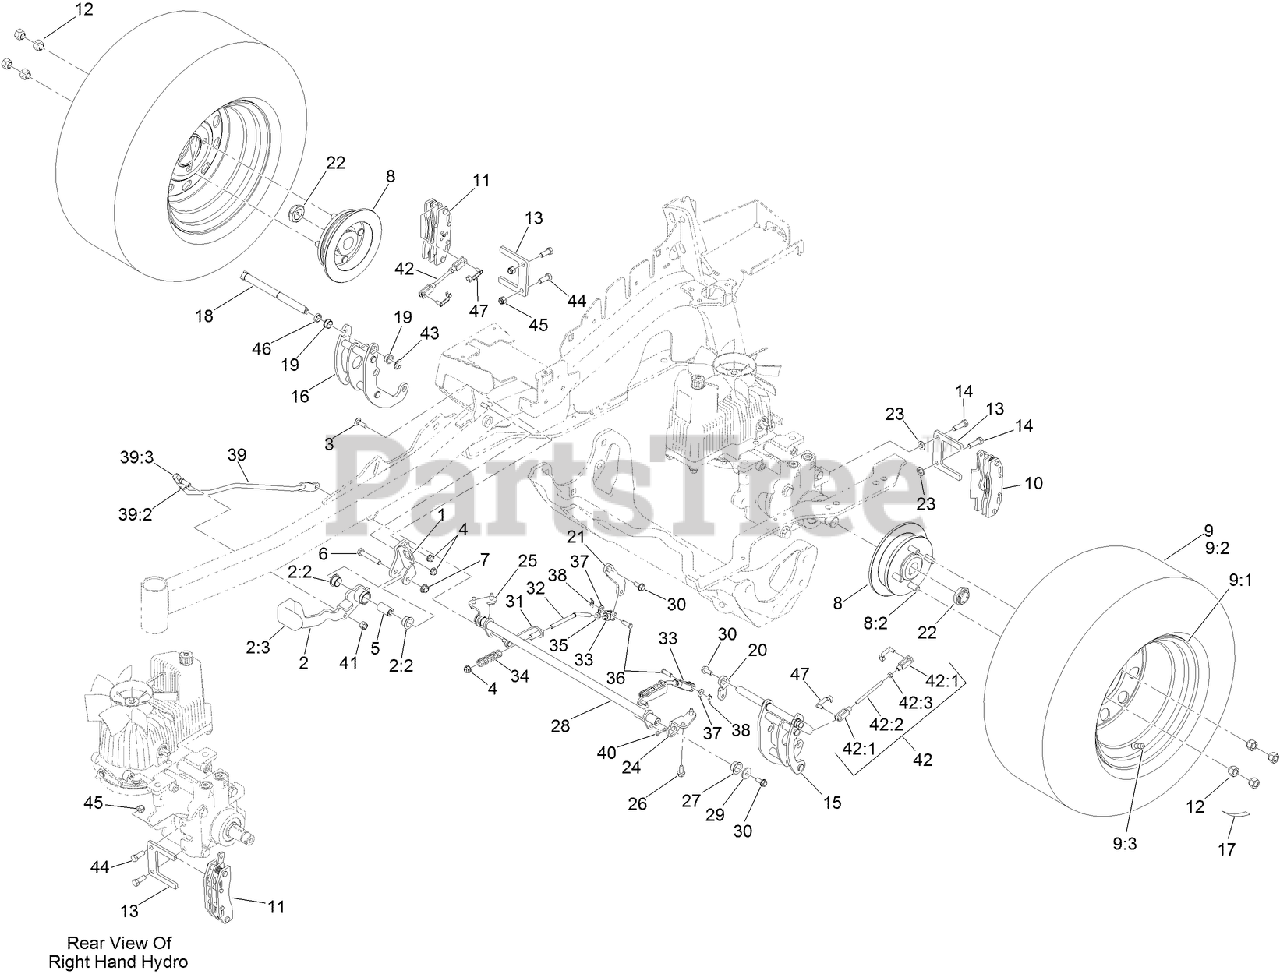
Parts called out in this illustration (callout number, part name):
1	BRACKET-MOUNT
2	BRAKE LEVER ASM W/ GRIP
2:2	BUSHING-FLANGE
2:3	GRIP-LEVER
3	BOLT-CARR
4	NUT-HF, NI
5	HANDLE-PIVOT, BRAKE
6	SCREW-HH
7	NUT-HF, NI
8	WHEEL HUB ASM
8:2	STUD-WHEEL
9	WHEEL AND TIRE ASM
9:3	STEM-VALVE
10	CALIPER-BRAKE
11	CALIPER-BRAKE, RH
12	NUT-LUG
13	PLATE-MOUNT, BRAKE
14	SCREW-LOCK, PATCH
15	MOUNT-BELLCRANK, LH
16	MOUNT-BELLCRANK, RH
17	DECAL-TORQUE, WHEEL HUB LUG
18	BELLCRANK
19	BUSHING
20	ARM-INNER, LH
21	ARM-INNER, RH
22	LOCKNUT
23	WASHER-FLAT
24	MOUNT-PIVOT, LH
25	MOUNT-PIVOT, RH
26	SCREW-HWHTF
27	BUSHING-FLANGE
28	SHAFT-CROSS
29	WASHER-FLAT
30	SCREW
31	BRACKET-L
32	LINKAGE-MID
33	YOKE-OFFSET
34	SPRING-COMPRESSION
35	NUT-JAM
36	PIN-CLEVIS
37	WASHER-PLAIN
38	PIN-COTTER, LOCKING
39	FRONT LINKAGE ASM
39:2	END-TIE ROD, RH
39:3	NUT-HJ
40	PIN-COTTER, LOCKING
41	NUT-LOCK
42	REAR LINKAGE ASM
42:1	YOKE
42:2	LINKAGE, REAR
42:3	NUT-JAM
43	E-RING
44	SCREW-HH
45	NUT-LOCK, NI
46	SPACER
47	PIN-CLEVIS, SPRING
